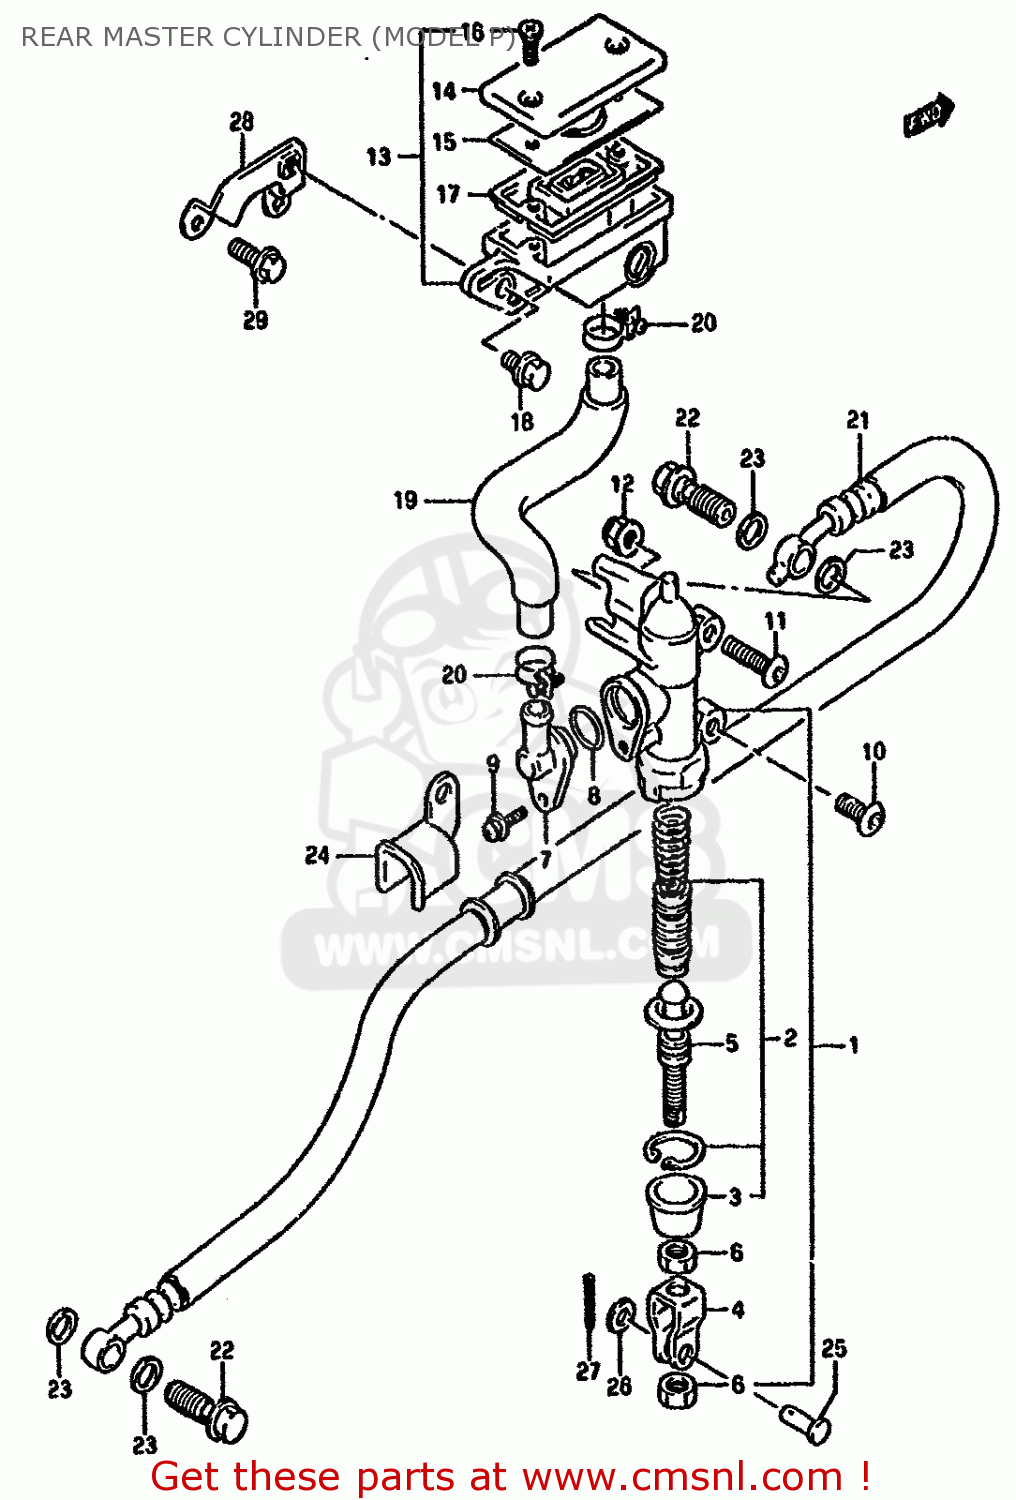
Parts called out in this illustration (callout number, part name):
1	CYLINDER ASSY,RR MASTER
2	PISTON/CUP SET
3	BOOT
4	YOKE
5	ROD,PUSH
6	NUT
7	CONNECTOR
8	O RING
9	SCREW
10	SCREW(6X16)
11	SCREW(6X30)
12	NUT
13	TANK ASSY,RR RESERVOIR
14	CAP
15	PLATE,DIAPHRAGM
16	SCREW
17	18
18	BOLT 6X12
19	HOSE,RESERVOIR TANK
20	CLAMP
21	HOSE,RR BRAKE
22	BOLT UNION
23	WASHER(10X15X1.5)
24	GUIDE,BRAKE HOSE
25	PIN
26	WASHER
27	PIN
28	PLATE,REAR RESERVOIR TANK
29	BOLT
